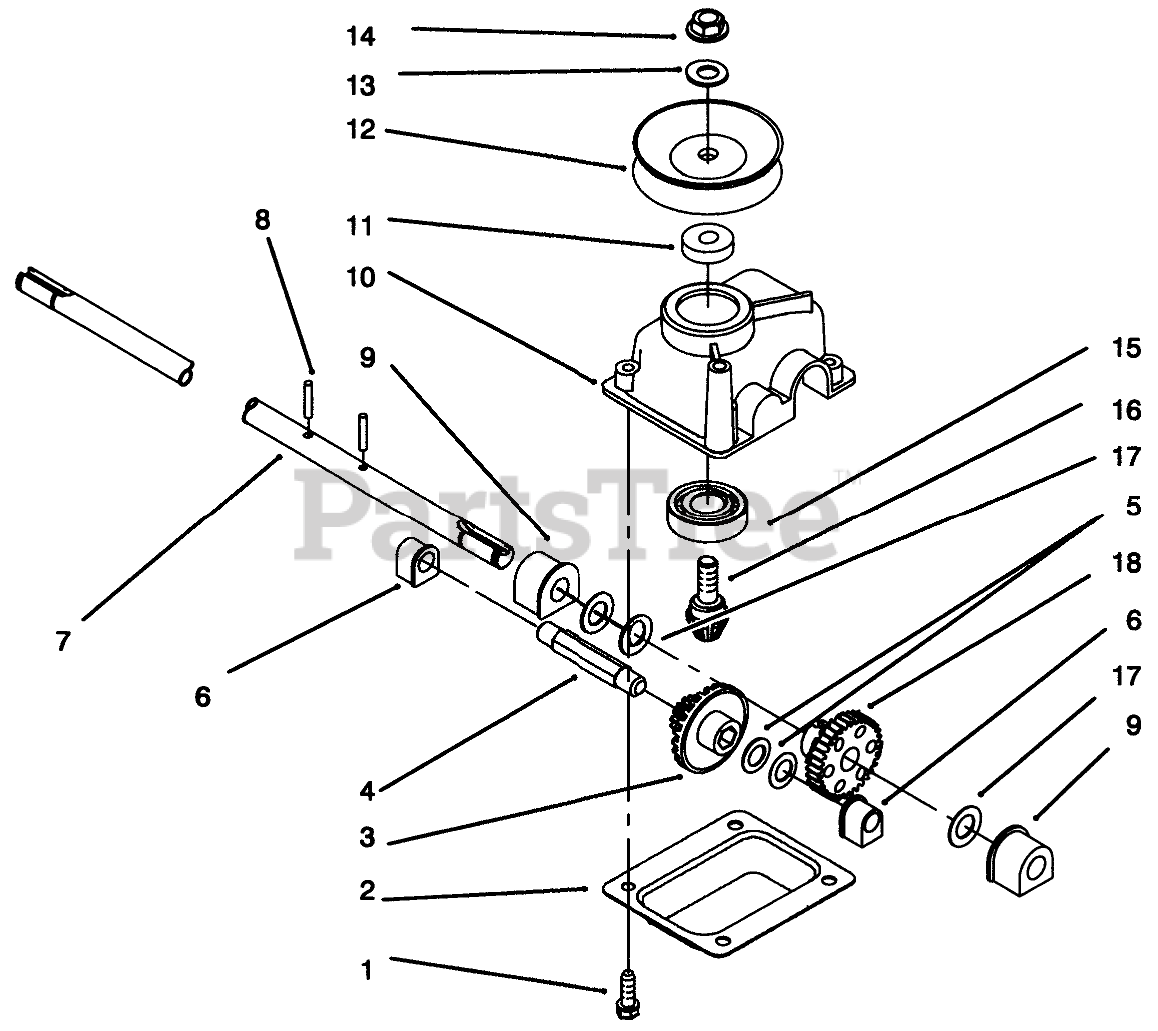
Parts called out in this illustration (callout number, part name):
1	SCREW-HWHTF
2	Cover-Gear Case
3	Gear-Bevel
4	SHAFT-INTERMEDIATE
5	WASHER-THRUST
6	BUSHING
7	OUTPUT SHAFT
8	SPIROL PIN H D
9	BUSHING
10	GEARCASE
11	SPACER
12	PULLEY-DRIVEN HALF
13	WASHER-FLAT
14	NUT-HEX
15	BEARING-BALL
16	Gear-Pinion
17	WASHER-PLAIN
